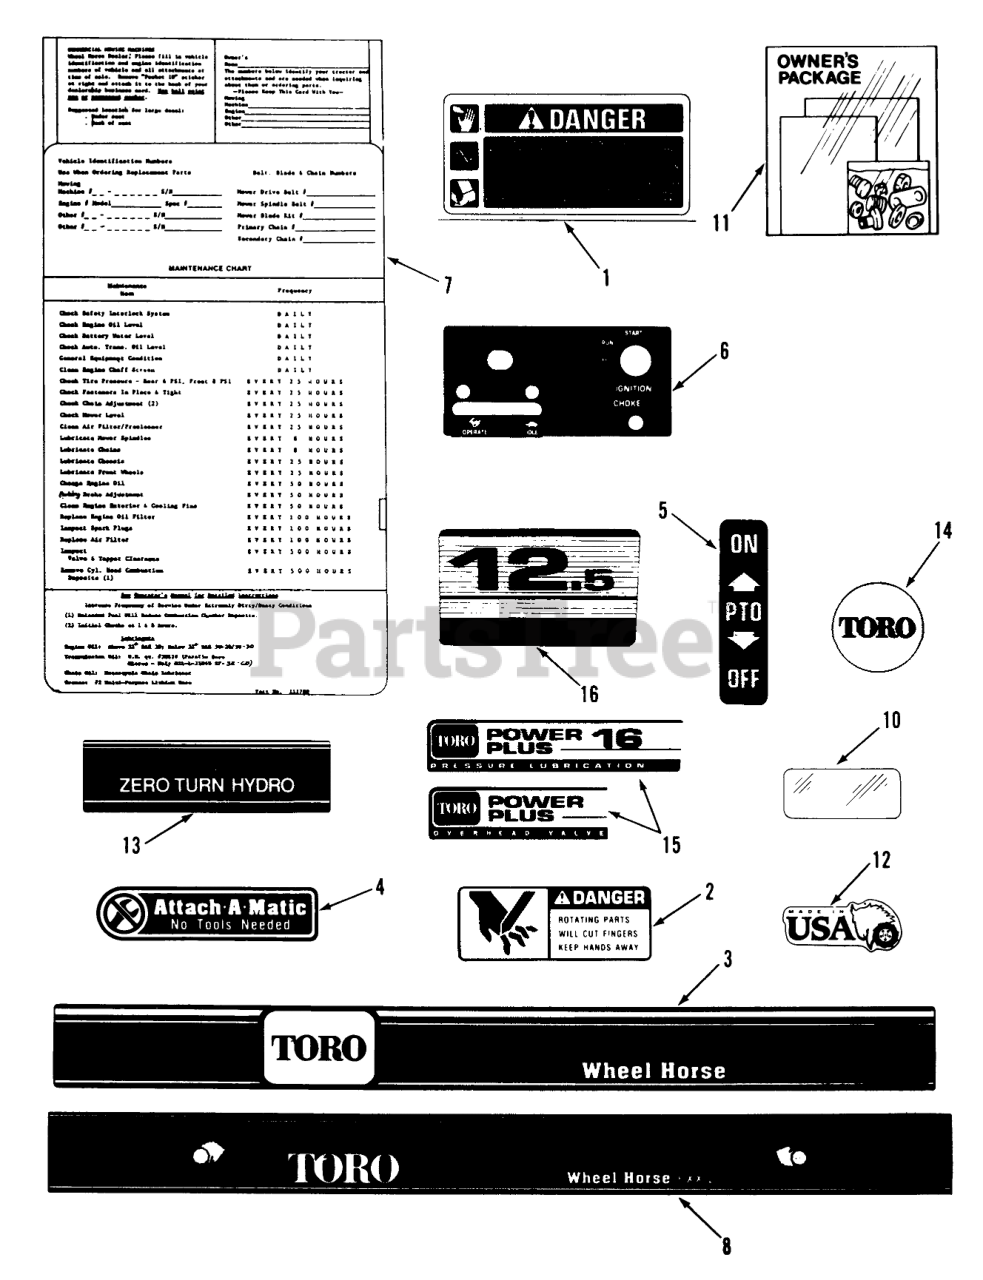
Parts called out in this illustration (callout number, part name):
1	DECAL-DANGER
2	DECAL-DANGER
3	DECAL-REAR 600
4	Decal-Attac-O-Matic
5	DECAL-PTO
6	DECAL-CONTROL
7	MAINTENANCE-DECAL
8	DECAL-FRONT 612-Z
10	DECAL-OVERLAY
11	Loose Parts Package 616-Z & 612-Z
12	Decal-Made In USA
13	DECAL-ZERO TURN HYD
14	NAME-PLATE TORO LOGO
15	DECAL POWER PLUS 16
16	DECAL-PWR PLUS 12.5
